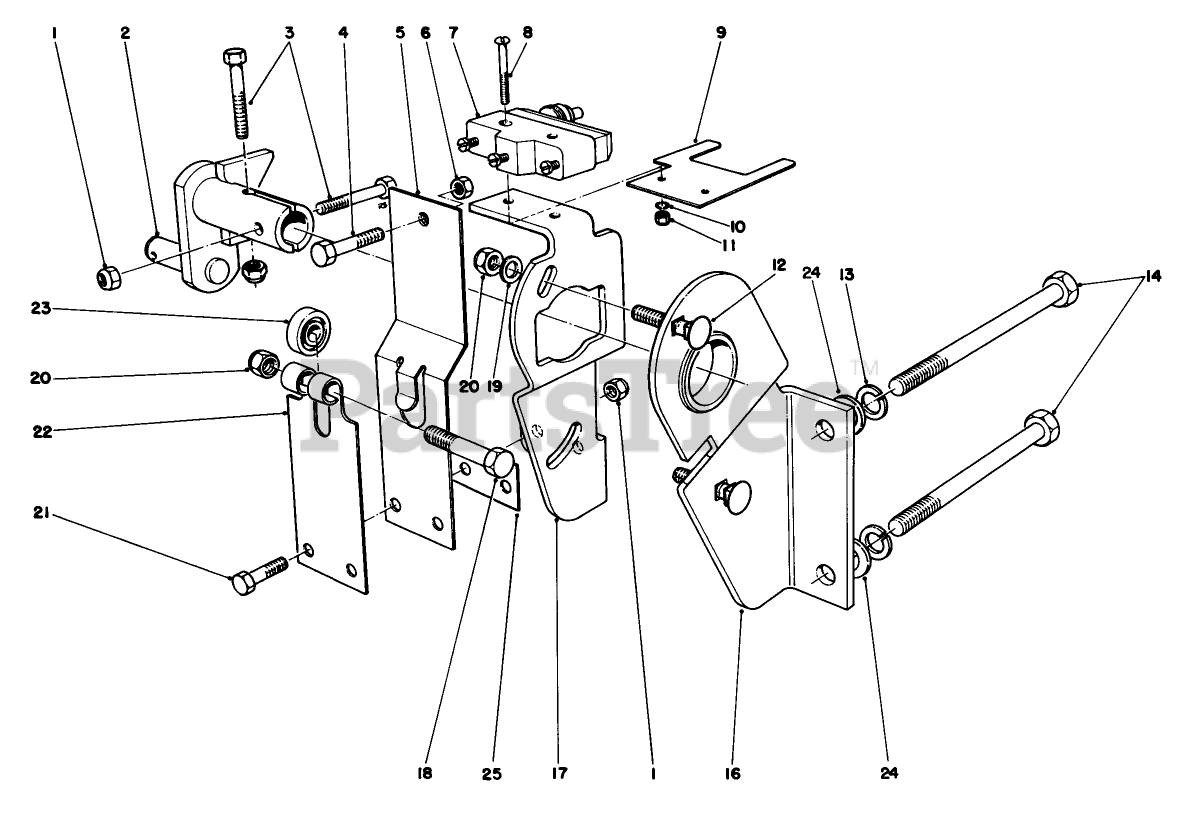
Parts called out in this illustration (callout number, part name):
1	NUT-LOCK, NI
2	Lever-Pump
3	SCREW-HH
4	SCREW-HH
5	EXTENDED LEAF SPRING ASM
6	NUT-HEX
7	Micro Switch
8	SCREW-MACHINE
9	STOP-SPRING, LEAF
10	WASHER-LOCK, INTERNAL
11	NUT-HEX
12	BOLT-CARR
13	WASHER-LOCK
14	SCREW-HH
15	SCREW-HH
16	Bracket-Mounting
17	PLATE-PUMP
18	SCREW-HH
19	WASHER-FLAT
20	NUT-LOCK, NI
21	SCREW-HH
22	SPRING-LEAF
23	NUT-LOCK, NI
24	BEARING-BALL
25	SHIM-ARM, SPRING
